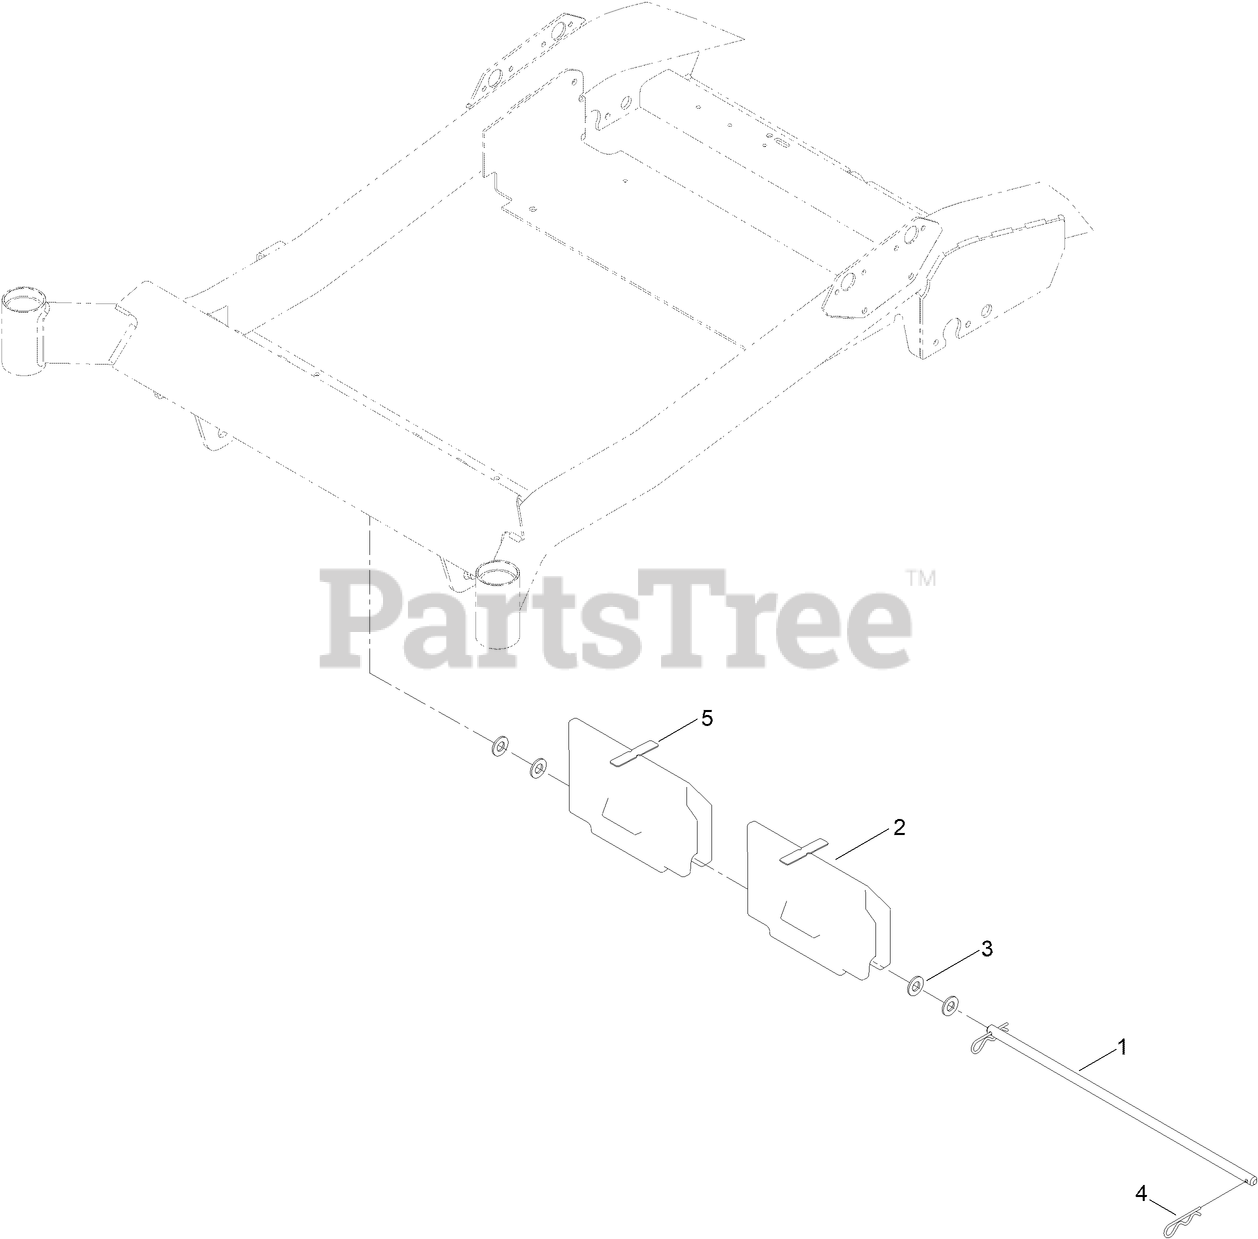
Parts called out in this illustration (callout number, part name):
1	ROD-DECK, PIVOT
2	WEIGHT-BAGGER
3	WASHER-FLAT
4	PIN-HAIR
5	BUMPER-PAD
